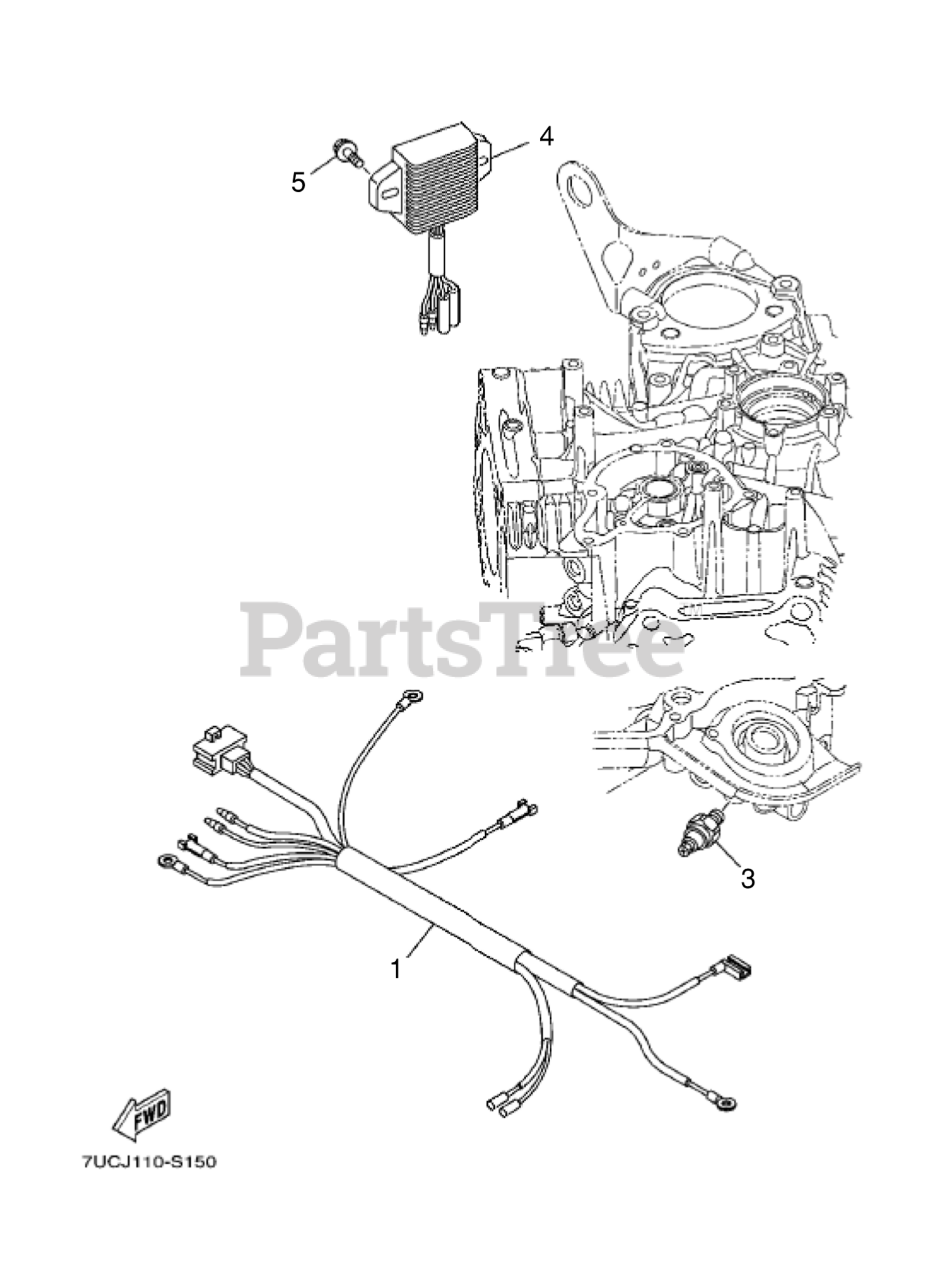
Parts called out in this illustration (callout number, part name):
1	WIRE LEAD YAMAHA PN: 7UC-H1115
3	SWITCH OIL PRESSURE ASSY YAMAH
4	REGULATOR AND RECTIFIER ASSY Y
5	BOLT YAMAHA PN: 95802-06020
